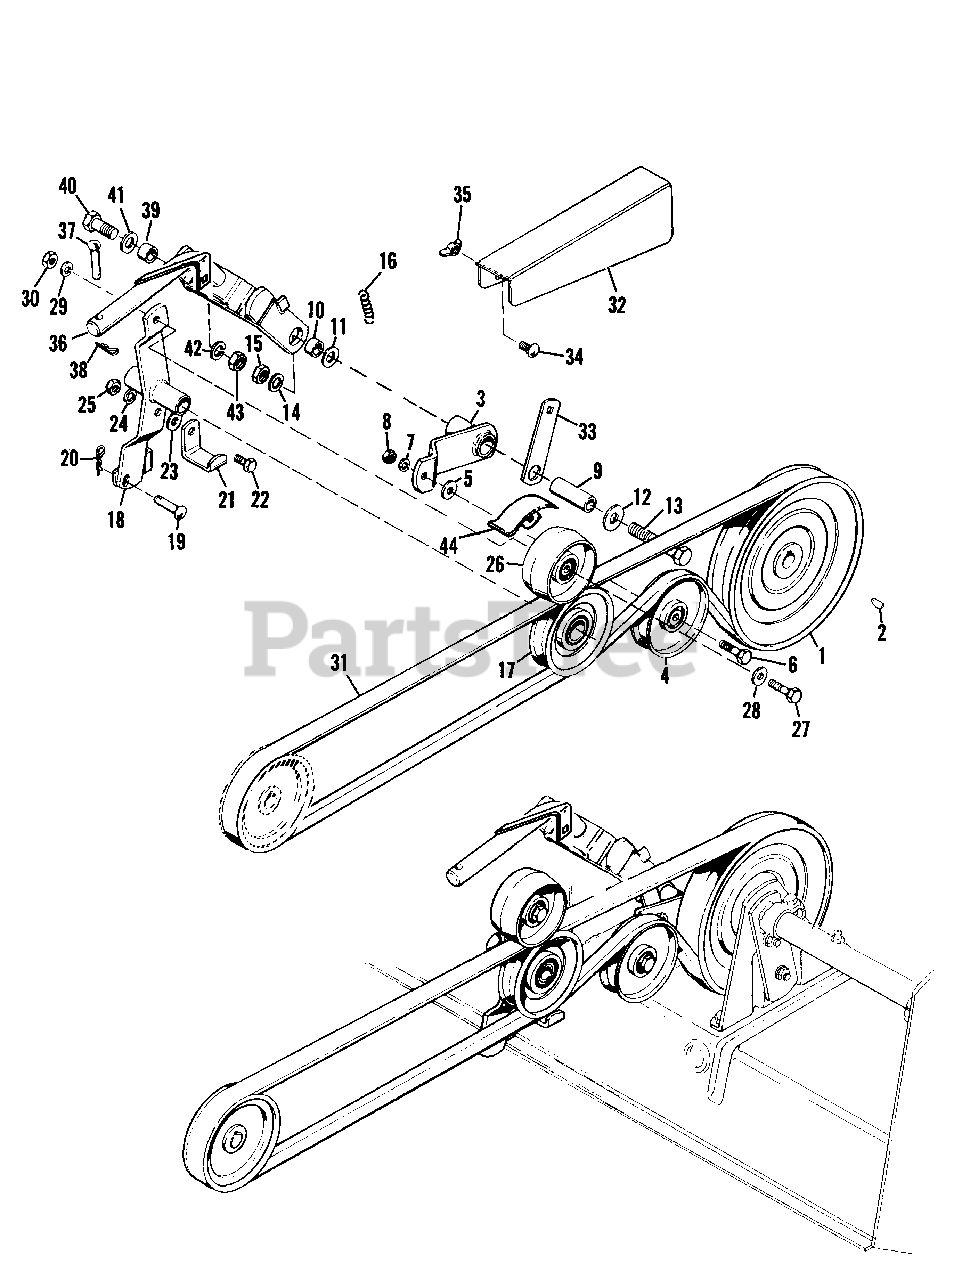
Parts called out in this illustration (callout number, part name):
2	KEY
3	CLUTCH LEVER ASSEMBLY
4	PULLEY, Idler
5	WASHER, Plain, 5/16"
6	CAPSCREW, Hex 3/8"-16 x 3" lg.
7	LOCKWASH E R, 3/8"
8	NUT, Hex, Full, 3/8"-16
11	WASHER, Plain, 3/8"
12	WASHER, Plain, 7/16"
13	CAPSCREW, Hex 7/16"-14 x 3-1/2" lg.
14	LOCKWASHER, 7/16"
15	NUT, Hex, Jam, 7/16"-14
17	PULLEY, Idler
18	IDLER ARM ASSEMBLY
20	CLIP, Spring
21	GUARD, Belt
22	CAPSCREW, Hex 3/8"-16 x 7/8" lg.
23	WASHER, Plain, 3/8"
24	LOCKWASHER, 3/8"
25	NUT, Hex, Full, 3/8"-16
26	PULLEY, Idler
27	CAPSCREW, Hex 3/8"-16 x 1-1/4" lg.
28	WASHER, Plain, 3/8"
29	LOCKWASHER, 3/8"
30	NUT, Hex, Full, 3/8"-16
32	GUARD, Belt
33	SUPPORT, Belt Guard
34	BOLT, Carriage 5/16"-18 x 3/4" lg.
35	NUT, Flange, 5/16"-18
36	LIFT BAR ASSEMBLY
37	PIN
38	CLIP, Spring
40	CAPSCREW, Hex 7/16"-14 x 1-1/4" lg.
41	WASHER, Plain, 3/8"
42	LOCKWASHER, 7/16"
43	NUT, Hex, Jam, 7/16"-14
